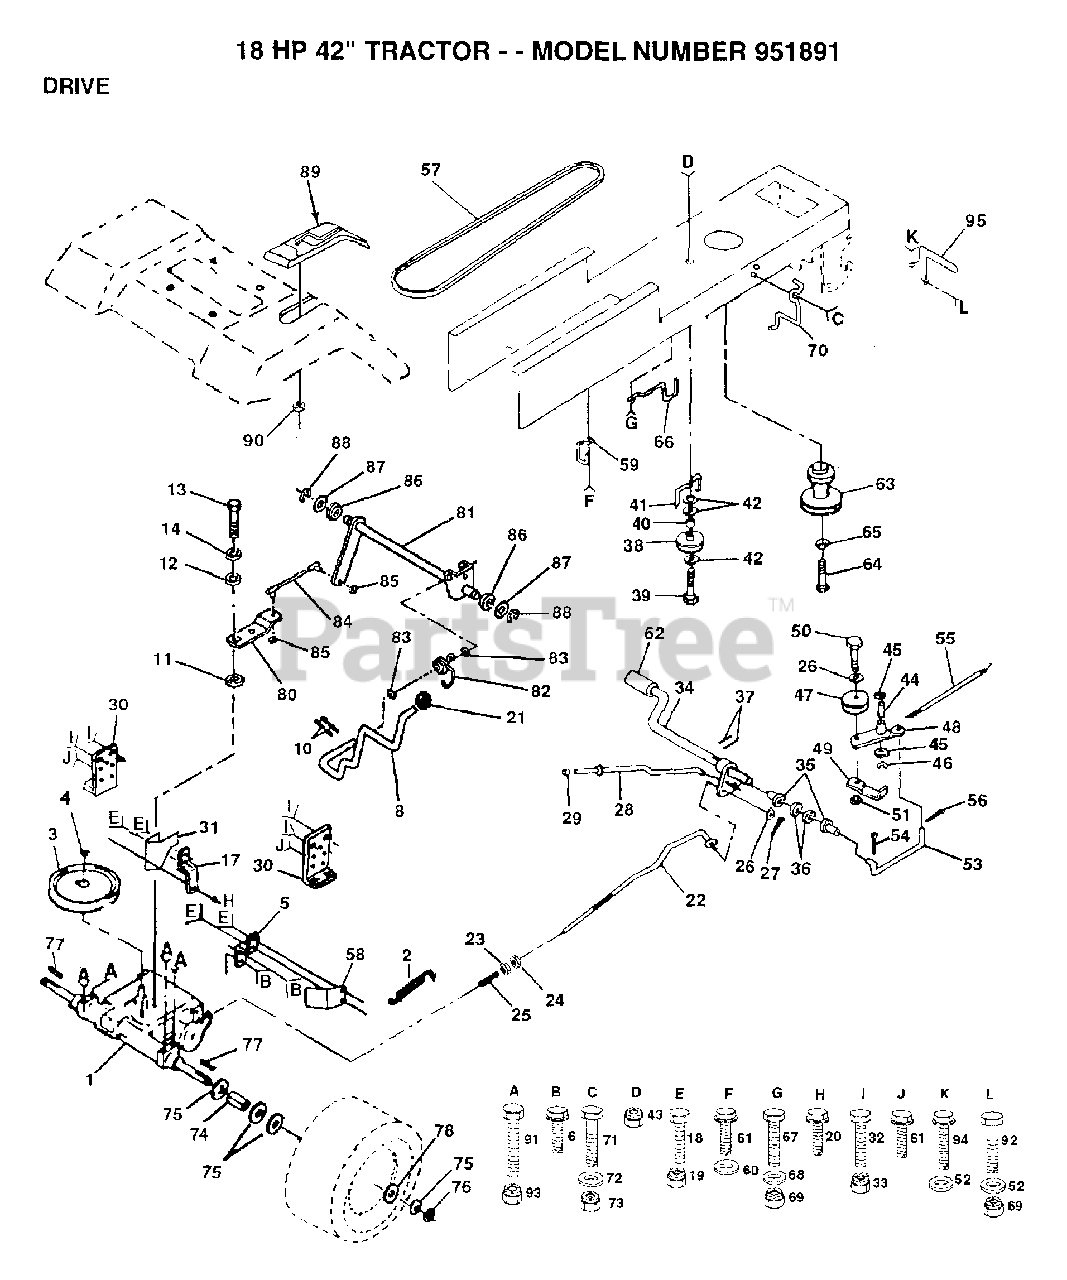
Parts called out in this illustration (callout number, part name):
3	"PULLEY,TRANSAXLE"
5	STRAP TORQUE
6	SCREW
10	PIN COTTER 1/8
11	WASH-SHFT PLT LT
12	WASHER
14	LOCKWASHER
17	STRAP TORQUE
20	SCREW
21	KNOB T (1/2-HOLE)
22	BRAKE ROD
23	NUT
24	NUT
25	SPRING ROD LT
26	WASHER
27	COTTER PIN
28	BRAKE PARK ROD
29	PLUNGER CAP T
30	TRANSAXLE MTG BKT
31	"KEEPER,BELT LH"
32	BOLT
35	NYLON BEARING
36	WASHER LT
38	PULLEY.IDLER.FLAT
39	BOLT
40	SPACER T
41	BELT KEEPER LT
42	WASHER
44	"LY, BEARING"
45	WASHER LT
46	KLIP RING
48	ARM IDLER
49	RETAIN BELT
52	WASHER HYT
53	"LINK, CLUTCH T"
54	COTTER PIN
55	"SPRING, RETURN LT"
56	COTTER PIN
57	BELT-V
58	"KEEPER,BELT RH"
60	WASHER
61	SCREW
62	PEDAL COVER T
64	BOLT
65	LOCKWASHER
66	KEEPER.BELT.ENG.L
67	BOLT
68	WASHER
70	KEEPER BELT ENG
71	BOLT
72	WASHER
74	SPACER LT
75	WASHER
76	E-RING LT
77	SQUARE KEY
78	WASHER
80	ARM SHIFT TRANS
81	SHAFT ASM.SHIFT
82	"SPRING,TORSION"
83	WASHER
84	TIE ROD
85	NUT 1/4-28
86	BUSHING
87	WASHER D
88	KLIP RING
90	NUT
91	BOLT
92	BOLT D
94	SCREW GTV
95	MUFFLER GUARD
